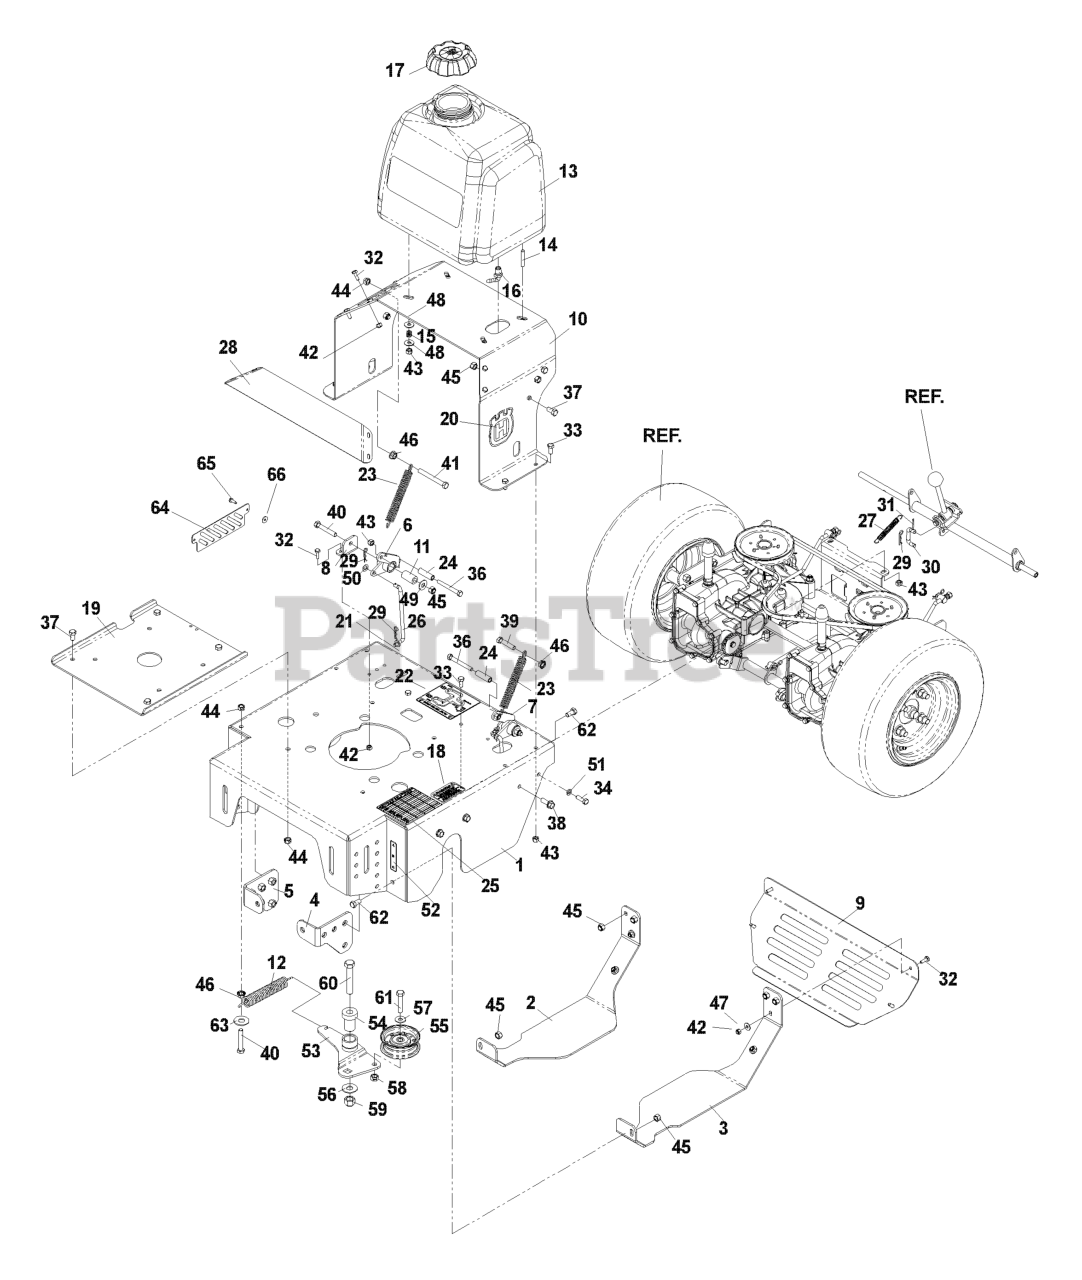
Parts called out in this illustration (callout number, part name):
1	REAR DECK W/ DECALS
2	SKID PLATE, RT
3	SKID PLATE, LT
4	NUT PLATE, LT
5	NUT PLATE, RT
6	BELLCRANK, RT, ETS
7	BELLCRANK, LT, ETS
8	CONTROL BRAKE
9	REAR GUARD
10	TANK SUPPORT
11	BUSHING, SLEEVE
14	STUD, 5/16C
16	HOSE BARB 90 DEGREE
17	FUEL CAP ANTI-SPLASH
18	DECAL, PROP. 65
19	ENGINE PLATE, ORANGE
20	DECAL, CROWN H
21	DECAL, BELT DRIVE
22	DECAL, BYPASS/BRAKE
23	SPRING-TRANS
25	DECAL, HEIGHT
26	CONTROL LINKAGE
28	PANEL, ORANGE
29	HAIRPIN #2
30	BRAKE ENGAGE LINKAGE
31	COTTER PIN 3/32 X 3/4
32	HCS 1/4C X 3/4 HCS
33	HCS 5/16C X 3/4
34	HCS 5/16C X 1
36	HCS 5/16C X 2-3/4
37	SCREW 3/8C X 3/4 HEX CAP
38	4CS 3/8C X 1 SERRATED HEAD
39	HCS 3/8C X 2 1/2
40	HCS 3/8C X 2 1/4
41	HCS 3/8C X 3 1/2
42	NUT.1/4-20.HEX.NYLOC.ZD
43	NUT 5/16 NYLOC
44	NUT 3/8C CENTERBLOCK
45	NUT 3/8-16 NYLOC
46	NUT 3/8C WHIZ
47	WASHER 1/4 FLAT
48	WASHER 5/16 FLAT
49	WASHER 3/8 FLAT
50	FLAT WASHER 5/16 SAE
51	WASHER.LOCK.HVY.HLCL.SPR.5/16
52	DECAL, POSITION
53	IDLER ARM WELDMENT
54	IDLER SPINDLE
55	IDLER PULLEY
56	WASHER 1/2 FLAT
57	WASHER 5/16 FLAT
58	NUT 3/8C CENTERBLOCK
59	NUT 1/2-13 HEX NYLOC ZD
60	HCS 1/2C X 2 3/4
61	HCS 3/8-16 X 1 3/4 GR5
62	HCS 3/8-16X1.GRD.5.ZD
63	WASHER 1/2" FLAT
65	SCREW #10 X 1/2 SELF TAPPING
66	WASHER #10
